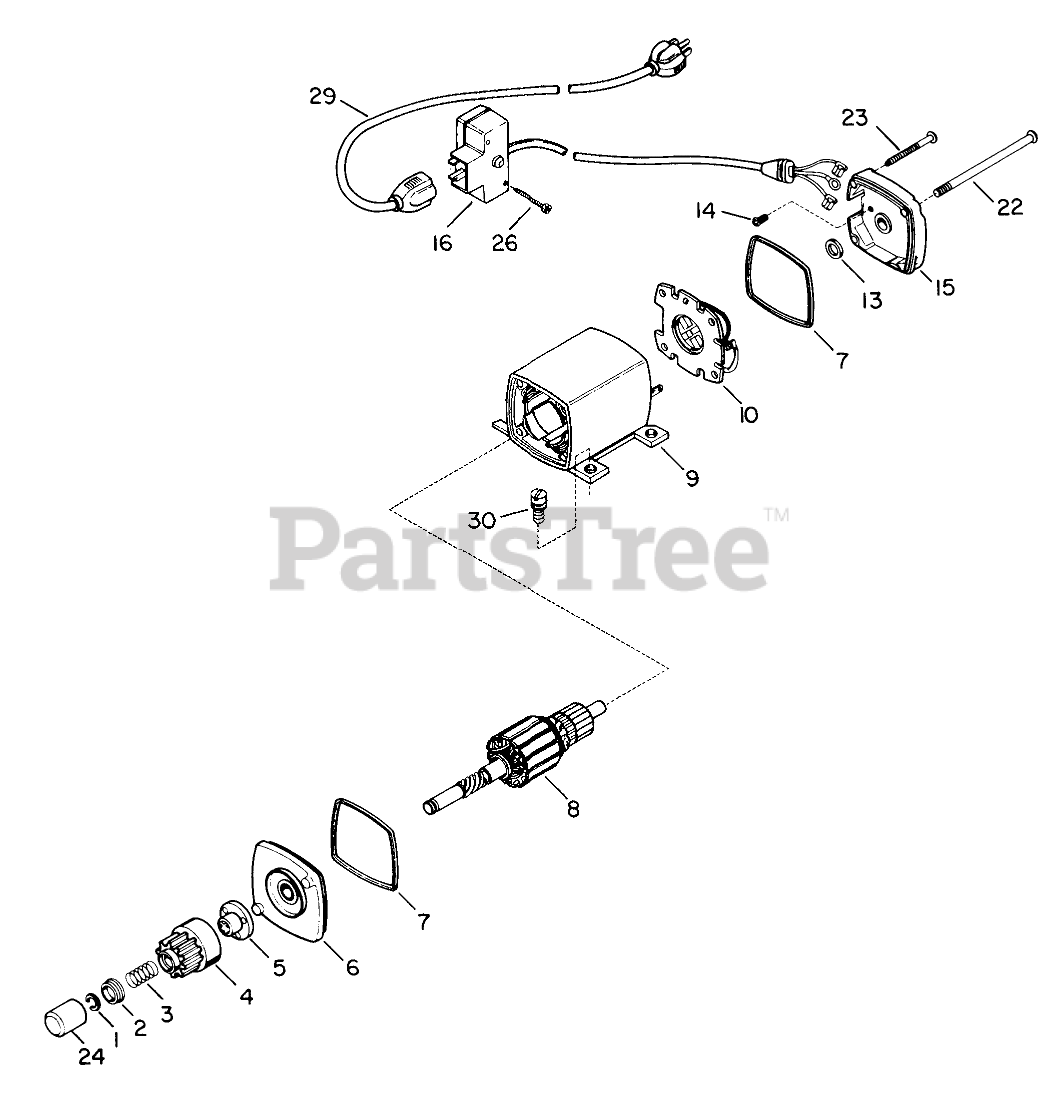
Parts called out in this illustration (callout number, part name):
1	Ring-Retainer
2	Retainer-Spring
3	Spring-Anti Drift
5	Nut-Engaging
6	Cap Assy., Drive End (Incl. Ref. #7)
8	Armature
9	Housing ASM
10	Card ASM
13	Washer-Thrust
14	Screw-Ground
15	Cap Assembly, Commutator End (Incl. Ref. #7)
16	Switch Box ASM
22	Bolt-Case
23	Screw-Ground
24	Cover-Dust
29	Cord-Extension
